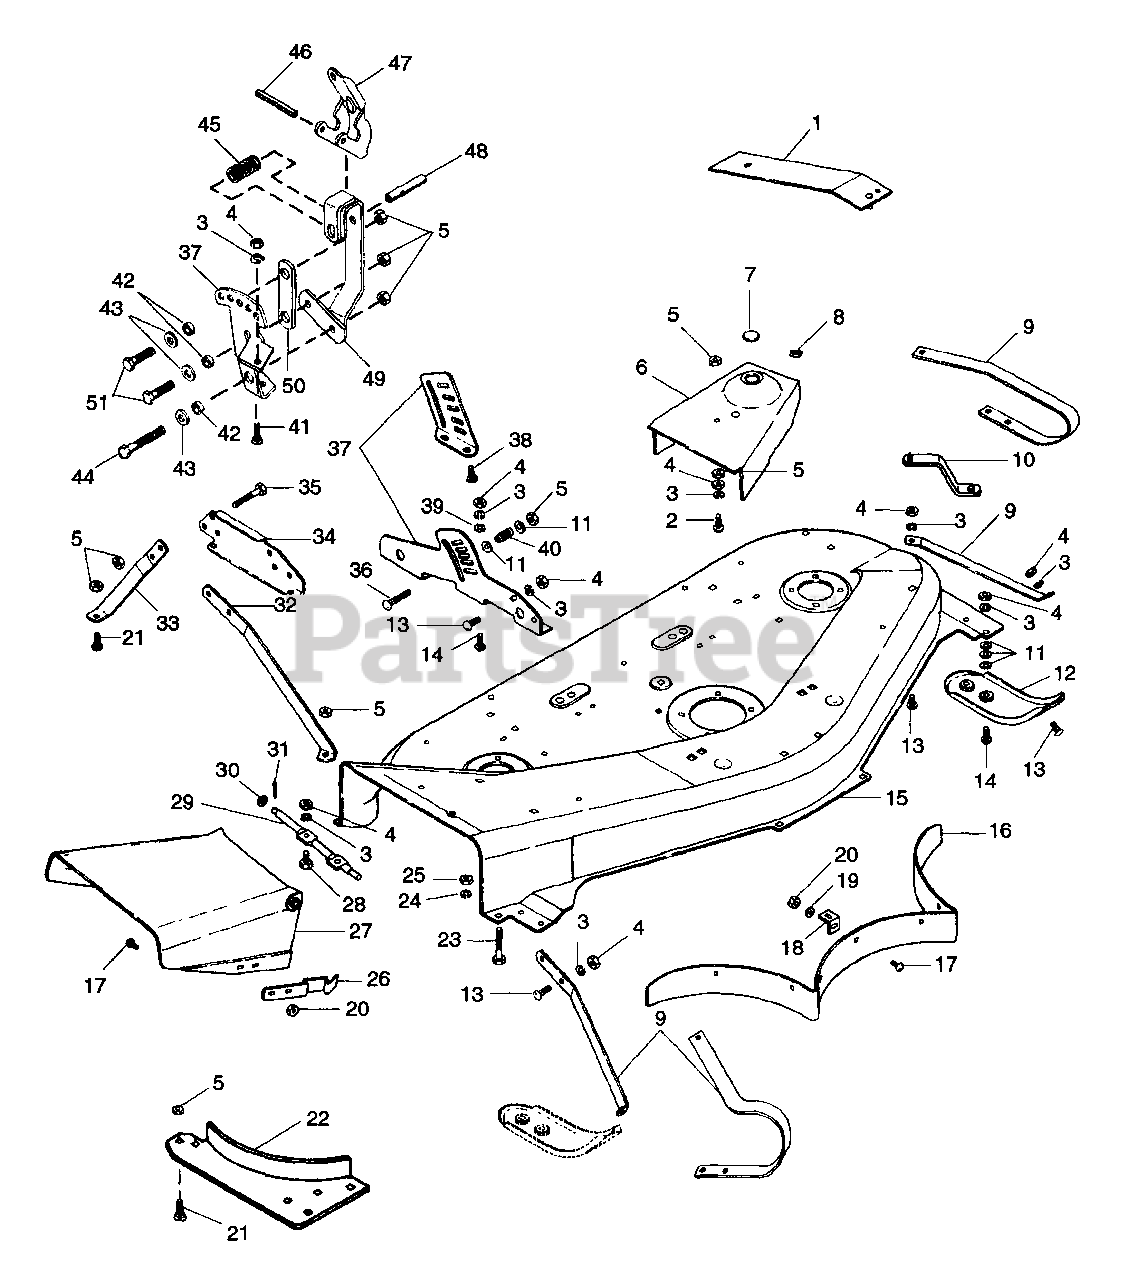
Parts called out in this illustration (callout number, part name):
2	BLT-RDHDSQNK .31-18X3.25 SHTPL
3	WSHR-LK .312X.097 PL HVY
4	NUT-HEX .312-18
5	NUT-LK .312-18 GR A PL
6	BELT COVER R H 42"
6	BELT COVER L H 42"
6	BELT COVER R H 48"
6	BELT COVER L H 48"
6	BELT COVER R H 60"
6	BELT COVER L H 60"
7	PLUG BUTTON 1.50
7	BUTTON PLUG 1.0
8	NUT-LK .312-18 GR A PL
8	NUT-LK-NYL.312-18 PL
9	SKID BRACE LH
9	SKID BRACE-RH
9	SKID BAR L.H.
9	SKID BAR R.H.
10	BRACE
11	WSHR-FL-STL .38X.875X.083 PL
12	SKID
13	BLT-RDHDSQNK .31-18X.75 GR5 PL
14	BLT-RDHDSQNK .31-18X1.00 PL
15	MOWER PAN W/DECALS 42"
15	MOWER PAN W/DECALS 48"- ORANGE
15	60 INCH MOWER PAN W/ DECALS
16	BAFFLE-42 IN PAN
16	BAFFLE
17	BLT-RDHDSQNK .25-20X.50 SHT PL
18	BAFFLE TAB
19	WSHR-FL-STL.281X.62X.065 PL
20	NUT-LK-CTR .250-20 PL
21	BLT-RDHDSQNK .312-18X.62 PL
22	DEFLECTOR
22	BLT-HEX.38-16X2.5FTHD GR2 YWZC
22	BLT-RDHDSQNK .38-16X2.00 SHTYW
24	WSHR-LK .375X.115 HVY PL
25	NUT-HEX .375-16
26	SPRING, FLAT
27	CHUTE EXTENSION
28	BLT-HEX .31-18X.75 PL GR5
29	HINGE PIN
30	WSHR-FL-STL.406X.812X.065PL
31	PIN-COTR .09X.75 PL
32	BRACE-RIGHT FRONT
33	BRACE-RIGHT REAR
34	BRACKET-BRACE
35	BLT-HEX .31-18X.75 PL GR2
36	BLT-RDHDSQNK .31-18X1.75 PL
37	QUADRANT
37	HEIGHT QUADRANT
38	BLT-RDHDSQNK.31-18X.75GR5SHTPL
39	WSHR-FL-STL .323X.625X.062 PL
40	SG-COMP .063X.53X1.187
41	BLT-SERRDHD SL .31-18X.75 YZ
42	SPACER BUSHING .5 X .32 X .21
43	WSHR-FL-STL .328X.875X.062 PL
44	BLT-HEX .31-18X1.25 PL GR5
45	SG-COMP .045X.50X1.187
45	PIN-ROLL .188X1.75
47	LEVER
47	PIN
49	HANDLE HEIGHT ADJ.
50	LINK
51	BLT-HEX .31-18X.88 PL GR2
